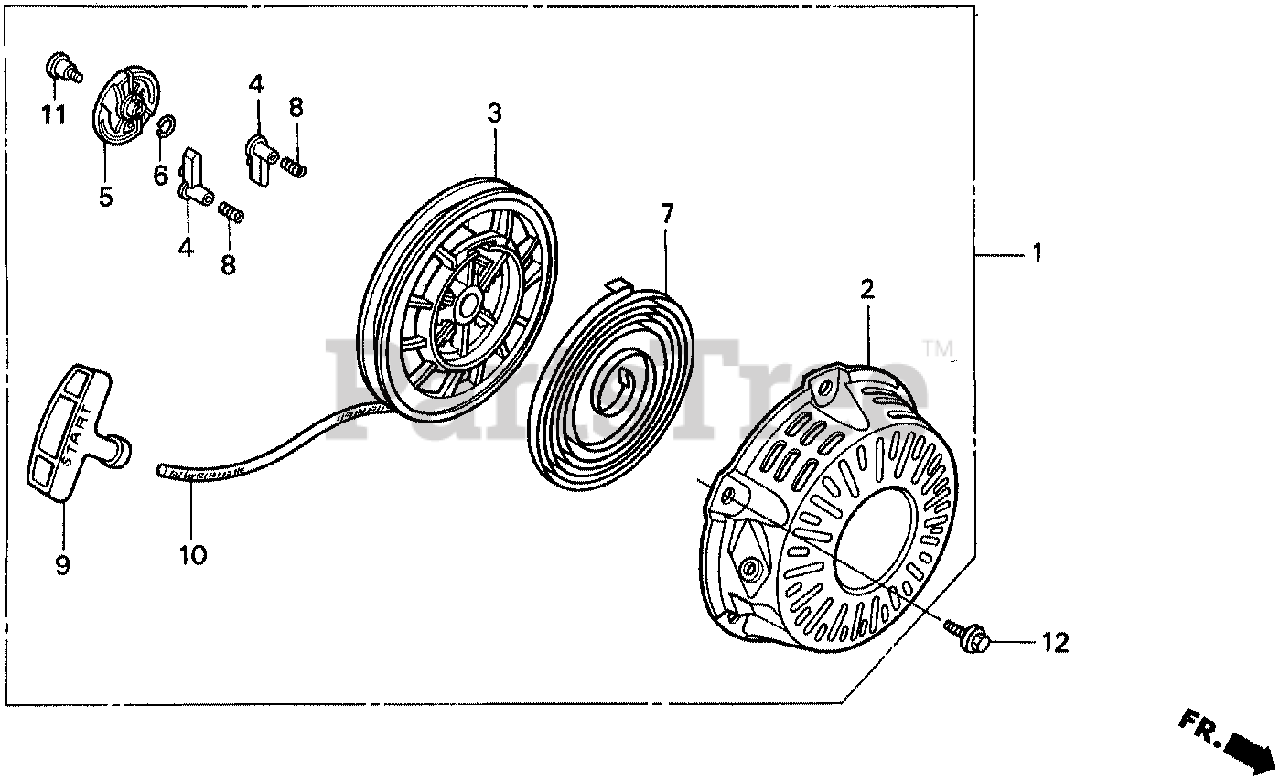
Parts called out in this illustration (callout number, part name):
1	STARTER ASSY., RECOIL *R8* (BRIGHT RED)
1	STARTER ASSY., RECOIL *T51* (JACOBSEN ORANGE)
2	CASE, RECOIL STARTER *R8* (BRIGHT RED)
2	CASE, RECOIL STARTER *T51* (JACOBSEN ORANGE)
3	REEL, RECOIL STARTER
4	RATCHET, STARTER
5	GUIDE, RATCHET
6	SPRING, FRICTION
7	SPRING, RECOIL STARTER
8	SPRING, RETURN
9	KNOB, RECOIL STARTER
10	ROPE, RECOIL STARTER (#5X55") (NA USE ALT:08550-ZG921-11)
11	SCREW, SETTING
12	BOLT, FLANGE (6X8)
